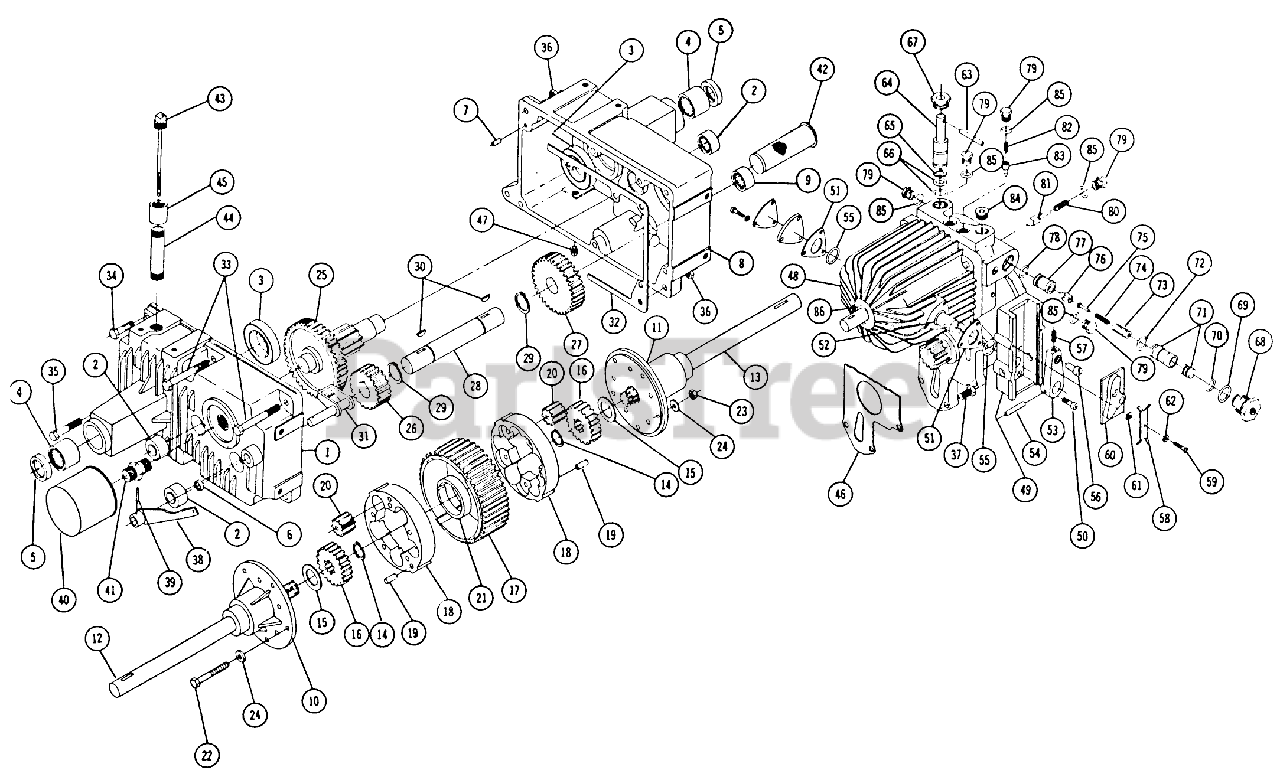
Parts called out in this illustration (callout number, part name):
1	Case R.H.
2	BEARING-NEEDLE
5	SEAL-OIL
7	PIN-DOWEL
16	SIDE GEAR
18	BULLT 252
22	Bolt Hex 3 1/4
23	3/8-16 E.S.
24	Washer
27	Gear-33 Teeth
30	Key
33	Bolt Hex 3/8-16 x 5
34	Bolt, 3/8 16 x 2
35	Bolt Hex 3/8-16 x 1
37	Bolt, 3/8-16 x 1
41	FITTING
44	Nipple 1/2 Pipe x 31/2
45	Coupling 1/2 Pipe
48	SRV BULLT 437B
53	Arm-Cam Follower
54	ROLL PIN 1/4 X 1-1/4
57	Set Screw-1/4-20 x 1/2
59	Bolt-Rd. Heed #8-32 x 1/2
60	CAM
61	Washer
62	Lockwasher
63	SPIROL PIN
70	O RING
72	O RING
80	SPRING-SUNDSTRAND
82	Spring Charge Pump Valve
85	O RING
